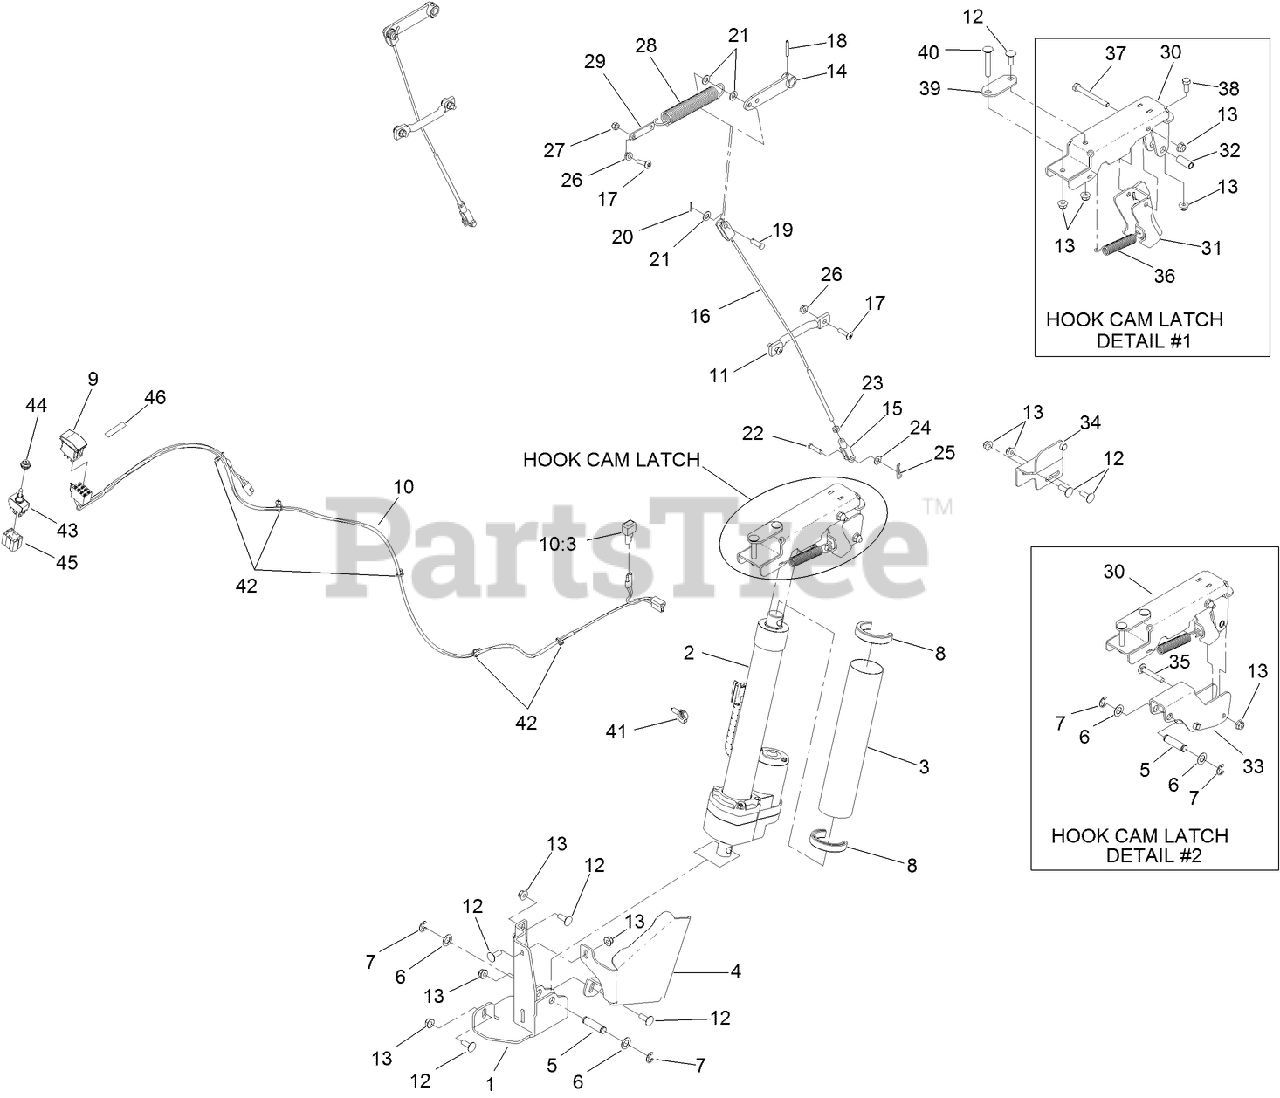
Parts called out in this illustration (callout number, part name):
1	BRACKET-HOPPER LIFT
2	ACTUATOR
3	TUBE-HEAT SHIELD
4	BRACKET-ACTUATOR SHIELD
5	PIN-CLEVIS
6	WASHER-PLAIN
7	RING-RETAINING, EXTERNAL
8	Trim-lok
9	SWITCH
10	HARNESS-WIRE
11	GUIDE-CABLE
12	BOLT-CARR
13	NUT-HF, NI
14	ARM-DOOR
16	CABLE ASM
17	SCREW-TTH
18	PIN-ROLL, SLOTTED
19	PIN-CLEVIS
20	PIN-COTTER
21	WASHER-PLAIN
23	NUT-JAM
24	WASHER-FLAT
25	PIN-COTTER
26	NUT-HF
27	NUT-LOCK, NI
28	SPRING-EXTENSION
29	PLATE-LINK, SPRING
30	BRACKET-LIFT, HOPPER
31	HOPPER LATCH ASM
32	SPACER
33	ACTUATOR LINK ASM
34	BRACKET-CAM
35	BOLT-CARR
36	SPRING-EXTENSION
37	SCREW-HH
38	SCREW-HH
39	PLATE-HOPPER, LEFT RETAINER
40	BOLT-CARR
41	CLIP-HARNESS
42	TIE-CABLE
43	SWITCH-TOGGLE, DPDT
44	BOOT-SWITCH, TOGGLE
45	CONNECTOR
46	DECAL-ACTUATOR
